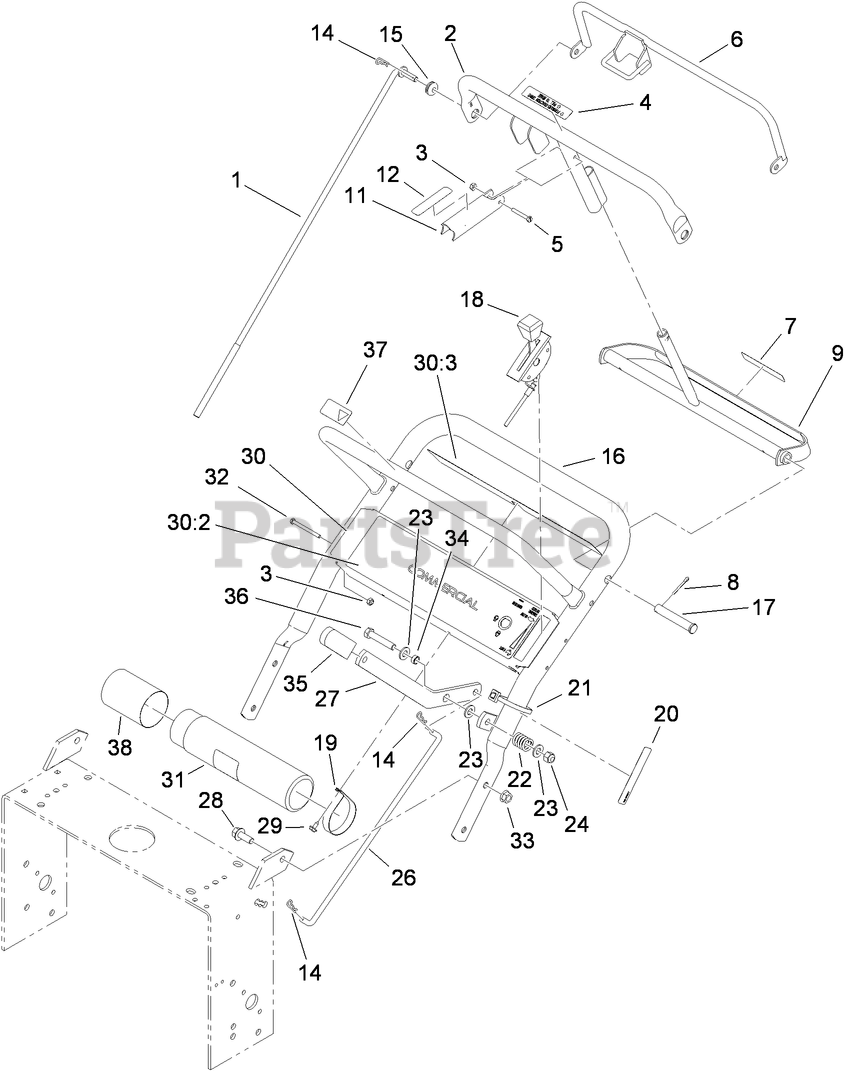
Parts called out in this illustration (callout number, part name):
1	ROD-CONTROL
2	BAR-CONTROL
3	NUT-LOCK, NI
4	DECAL
5	SCREW-SHH
7	DECAL
8	PIN-COTTER
9	CONTROL-PIVOT
11	LEVER-BRAKE, PARKING
12	DECAL
14	PIN-COTTER
15	GROMMET-RUBBER
16	HANDLE-UPPER
17	PIN-CLEVIS
18	CABLE-THROTTLE
19	CLAMP-R
20	DECAL-ENGAGE, DECK
21	TIE-PLASTIC
22	SPRING-COMPRESSION
23	WASHER-FLAT
24	NUT-LOCK, NI
26	LINKAGE-DRIVE, BLADE
27	LEVER-ENGAGEMENT, BLADE
28	SCREW-HHF
29	SCREW-HWHTF
30	CONTROL PANEL ASM
30:2	DECAL-PANEL, CONTROL
30:3	DECAL-DANGER
31	TUBE-MANUAL
32	SCREW-SHH
33	NUT-HF
34	SPACER
35	GRIP-LEVER
36	SCREW-HH
37	DECAL-PROTECTION, EAR
38	CAP-HOUSING
